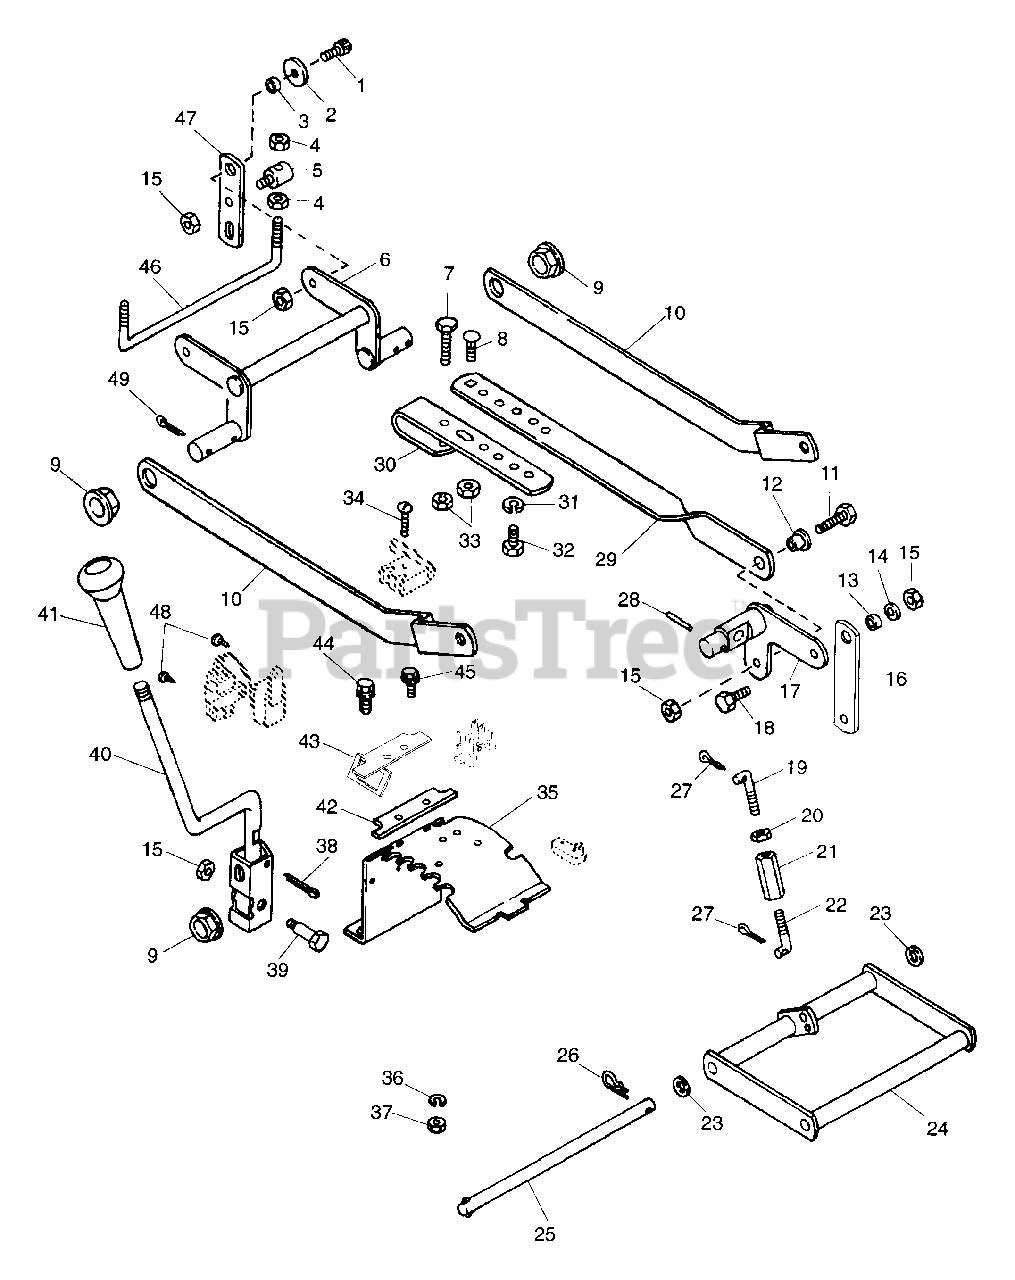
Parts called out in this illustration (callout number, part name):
1	SCR-SKH .31-18X.75 BTNHD YWZC
2	WSHR-FL-STL .344X1.125X.063PL
3	SPACER BUSHING .5 X .32 X .21
4	NUT-LK-JAM-CTR .375-16 PL
5	ROD PIVOT
6	REAR MOWER HANGER
7	BLT-HEX .38-16X1.50 PL GR2
8	BLT-RDHDSQNK .38-16X.75 SHT PL
9	FLANGE BUSHING
10	POSITIONING ARM
11	BLT-HEX .31-18X1.25 PL GR2
12	SPACER -SHLD .344X.500X.469
13	SPACER BUSHING .5 X .32 X .163
14	WSHR-FL-STL .323X.625X.062 PL
15	NUT-LK .312-18 GR A PL
17	MOWER LIFT ARM
18	BLT-HEX .31-18X.75 PL GR2
19	LINK - FRONT LIFT
20	NUT-LK .375-16
21	NUT-CUPLG RH & LH THD .37-16PL
22	LINK-FRONT LIFT
23	WSHR-FL-STL .520X.827X.062 YZ
24	FRONT LIFT ARM
25	HANGER PIN
26	PIN-HAIR INT .08X.38X1.42 YWZC
27	PIN-COTR .09X.75 PL
28	PIN-ROLL .188X1.25
29	LIFT STRAP
30	ADJUSTMENT STRAP
31	WSHR-LK .375X.115 HVY PL
32	BLT-HEX .38-16X.75 PL GR2
33	NUT-LK-CTR .375-16 GR A PL
34	SCR-MCH 10-24X1.00 SLRH PL
35	QUADRANT
36	WSHR-LK 10X.047 MED PL
37	NUT-HEX 10-24 PL
38	PIN-COTR .15X1.50
39	SHOULDER BOLT .436 X .912
42	STOP
43	REINFORCEMENT STOP
44	SCR-TAP .312-18X.50 HWH PL TR
45	SCR-TAP .250-20X.37 HWH PL TR
46	ROD - REAR LIFT
47	LINK - REAR LIFT
48	SCR-TAP 12-14X.50 CRPH PL
49	PIN-COTR .09X1.0 PL
